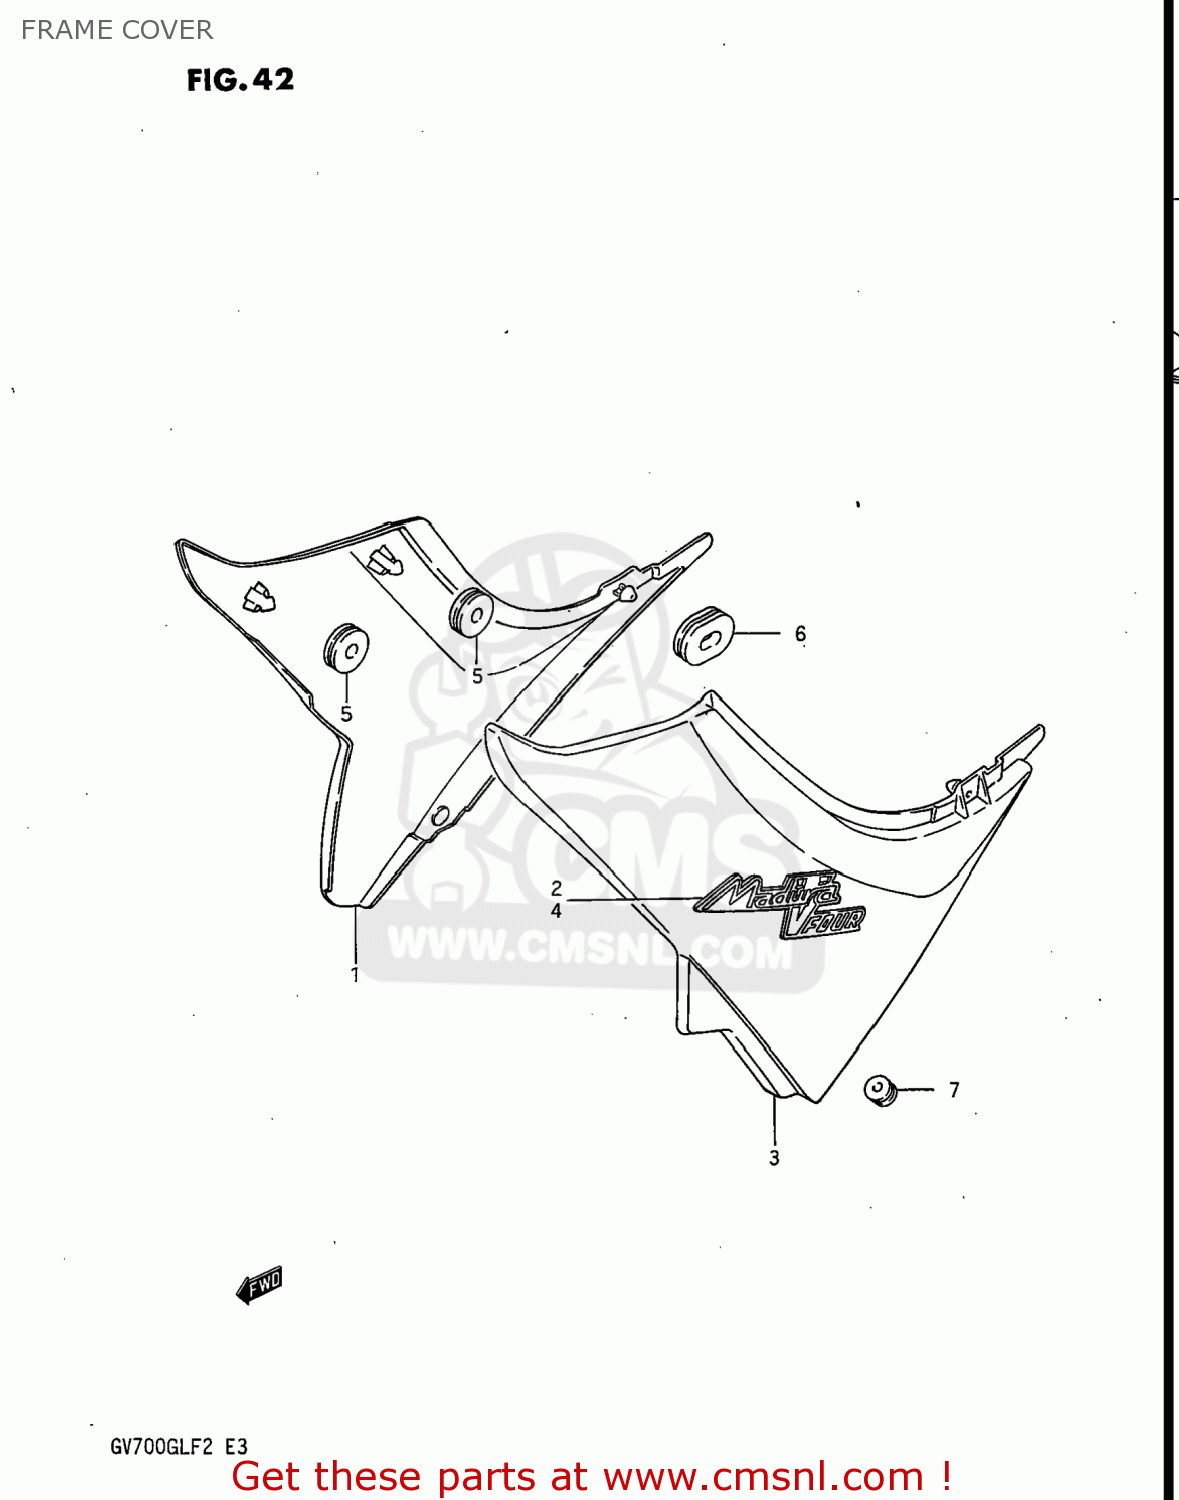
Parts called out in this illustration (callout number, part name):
1	COVER,FRAME,RIGHT
2	EMBLEM
3	COVER,FRAME,LEFT
4	EMBLEM
5	CUSHION
6	CUSHION
7	CUSHION
